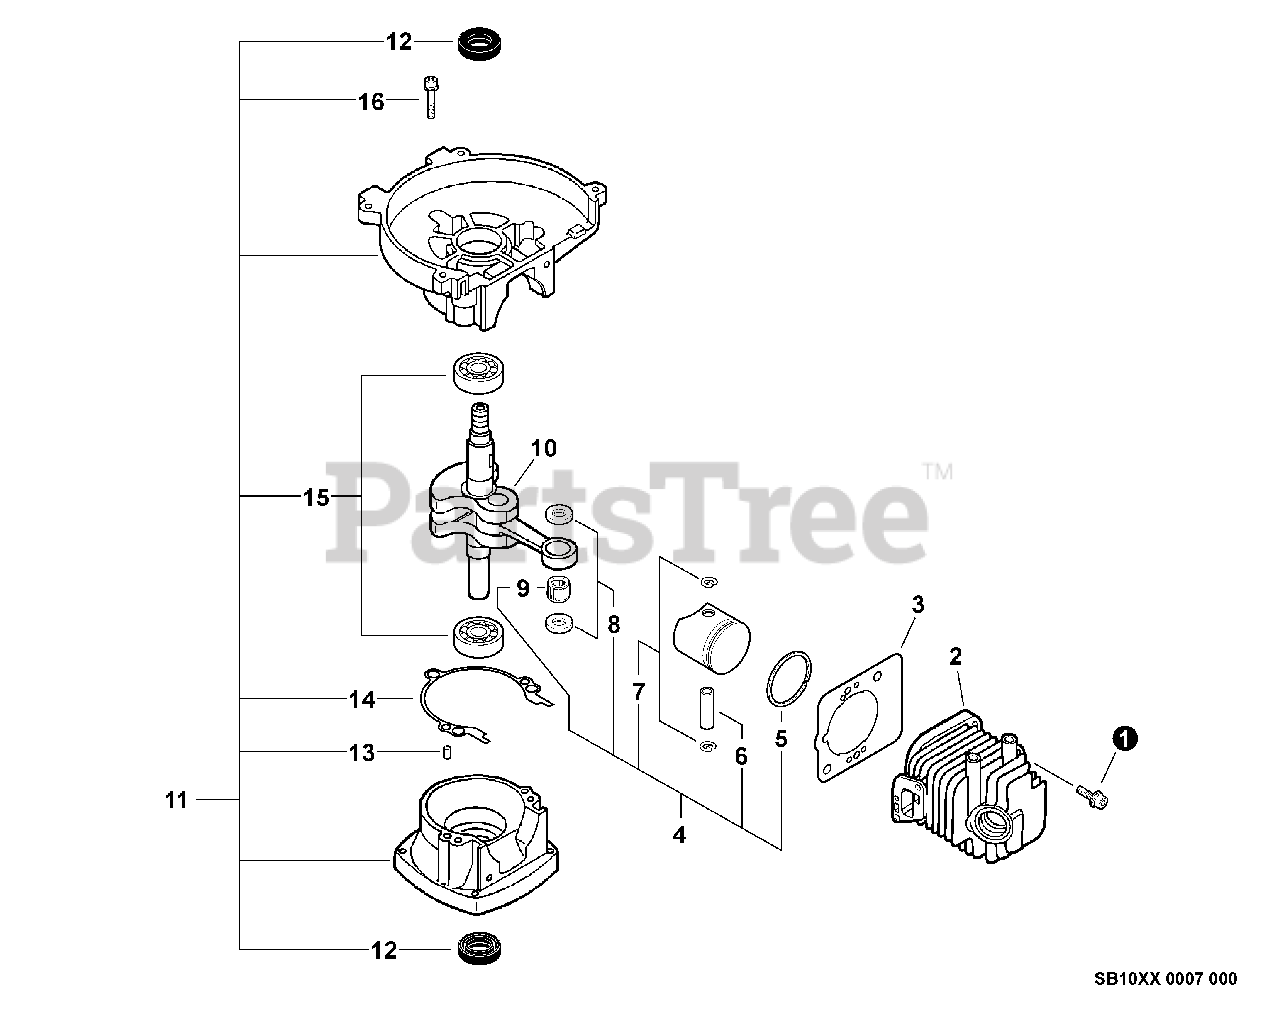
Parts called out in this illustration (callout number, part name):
1	BOLT 5×22
2	CYLINDER
3	GASKET, CYLINDER
4	PISTON KIT
5	RING, PISTON
6	PIN, PISTON 8
7	RING, SNAP
8	WASHER, THRUST
9	BEARING, NEEDLE
10	CRANKSHAFT ASSY
11	CRANKCASE KIT
12	SEAL, OIL 12
13	PIN, LOCATING 4
14	GASKET, CRANKCASE
15	BEARING, BALL - 6201 C3
16	BOLT 5×28
